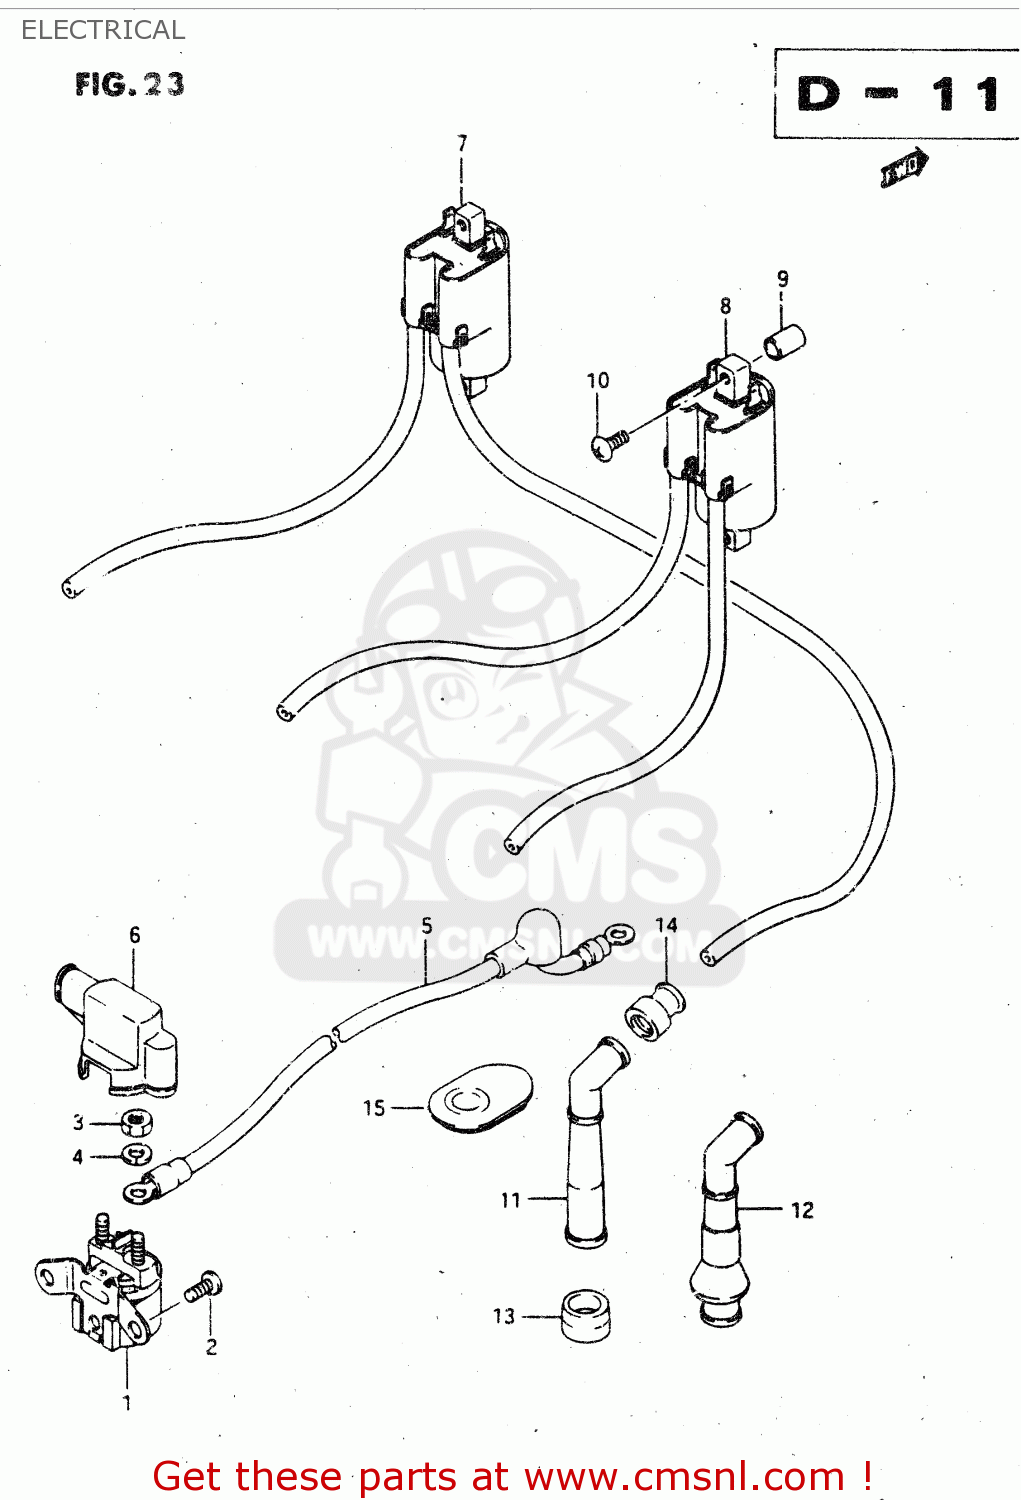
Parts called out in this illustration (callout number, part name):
1	RELAY ASSY,STARTING MOTOR
2	SCREW
3	NUT
4	WASHER,LOCK
5	WIRE,STARTER MOTOR LEAD
6	CAP,STARTER RELAY
7	COIL ASSEMBLY,IGNITION
8	COIL ASSEMBLY,IGNITION
9	SPACER
10	SCREW
11	CAP,SPARK PLUG
12	CAP, SPARK PLUG
13	SEAL,SPARK PLUG
14	SEAL,SPARK PLU
15	COVER,SPARK PLUG CAP
